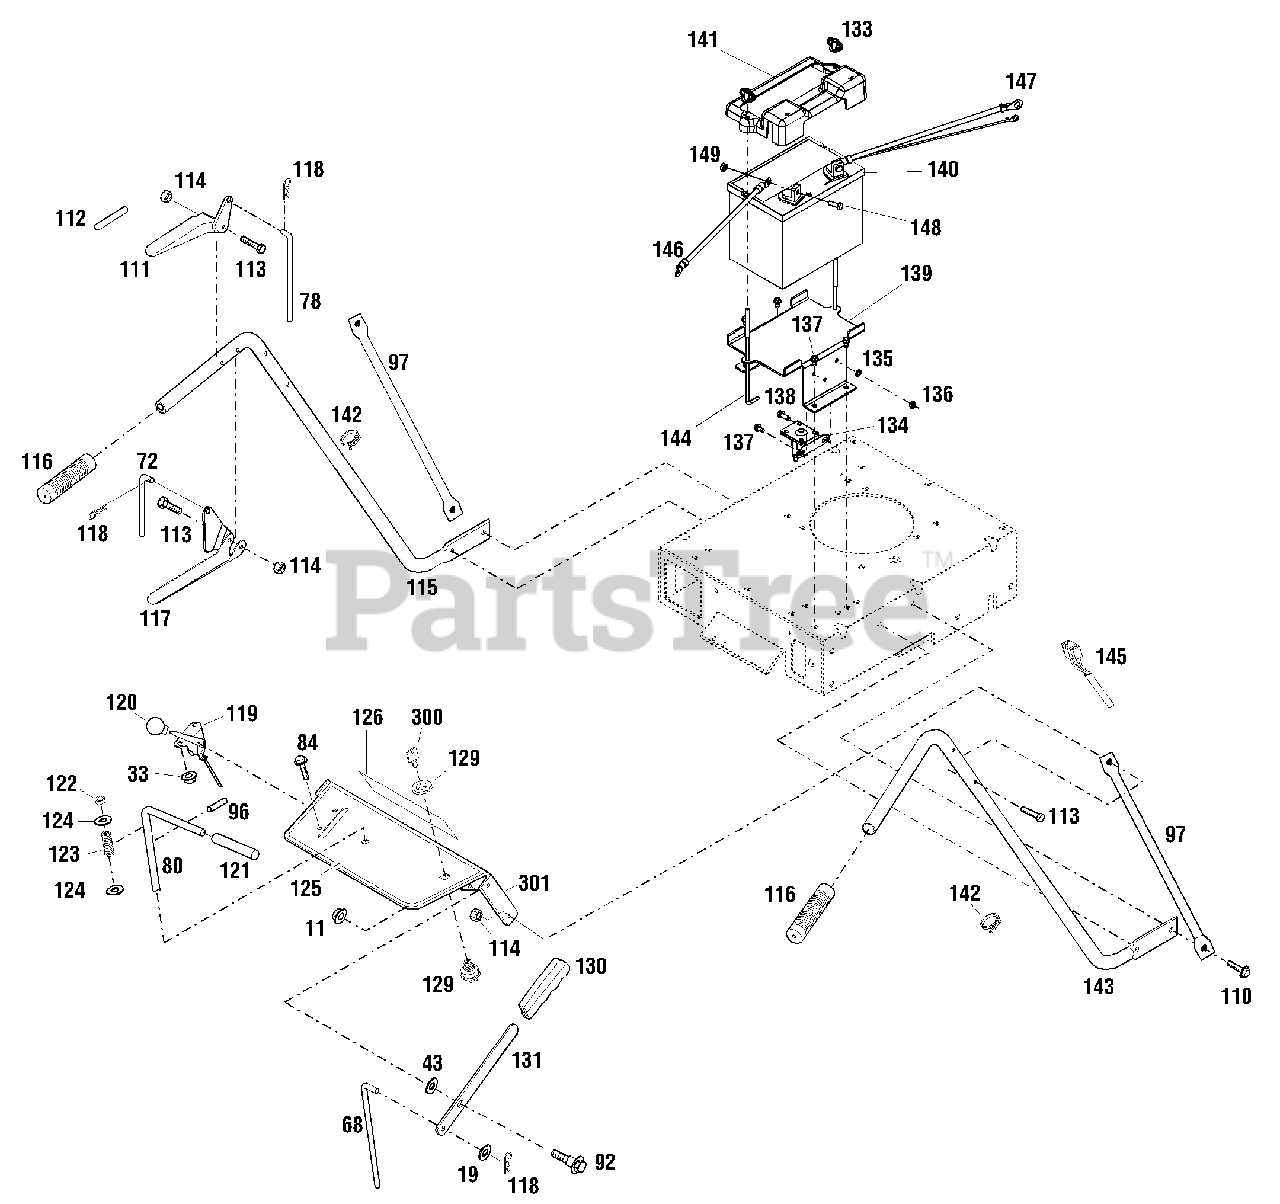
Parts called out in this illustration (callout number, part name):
11	Flange Locknut, 3/8-16
19	Flat Washer, 5/16
33	Flange Locknut, 1/4-20
43	Flat Washer, 1/2
68	Upper Blade Rod
72	Upper Transmission Rod
78	Upper Brake Rod
80	Shift Rod
84	Flange Lock Screw, 1/4-20 x 1/2
92	Shoulder Bolt
96	Roll Pin, 1/4 x 2-1/4
97	Brace, Handlebar
110	Flange Lock Screw, 5/16 x 3/4
111	Control Handle
112	Operator Presence Control Decal
113	Screw, 1/4-20 x 1-3/4, Grade 8
114	Locknut, 1/4-20
115	Left Handlebar
116	Handle Grip
117	Control Handle
118	Hair Pin, 5/64
119	Throttle Control
120	Knob
121	Handle Grip
122	Nylon Bushing
123	Compression Spring
124	Flat Washer, 1/2
125	Warning Decal
126	Logo Decal
129	Ignition Switch
130	Handle Grip
131	Mower Engage Lever
133	Wing Nut, 1/4-20
134	Solenoid
135	External Lock Washer, 1/4
136	Jam Nut, 1/4-20
137	Self-tapping Screw, 1/4-20 x 1/2
138	Self-tapping Screw, 1/4-20 x 3/4
141	Battery Cover
142	Plastic Tie
144	Battery Hold-down Rod
145	Wiring Harness
146	Red Wire, 12"
147	Black Wire, 14"
148	Hex Screw, 1/4-20 x .75
149	Hex Sems Nut, 1/4-20
300	Ignition Key
301	Console Assembly
